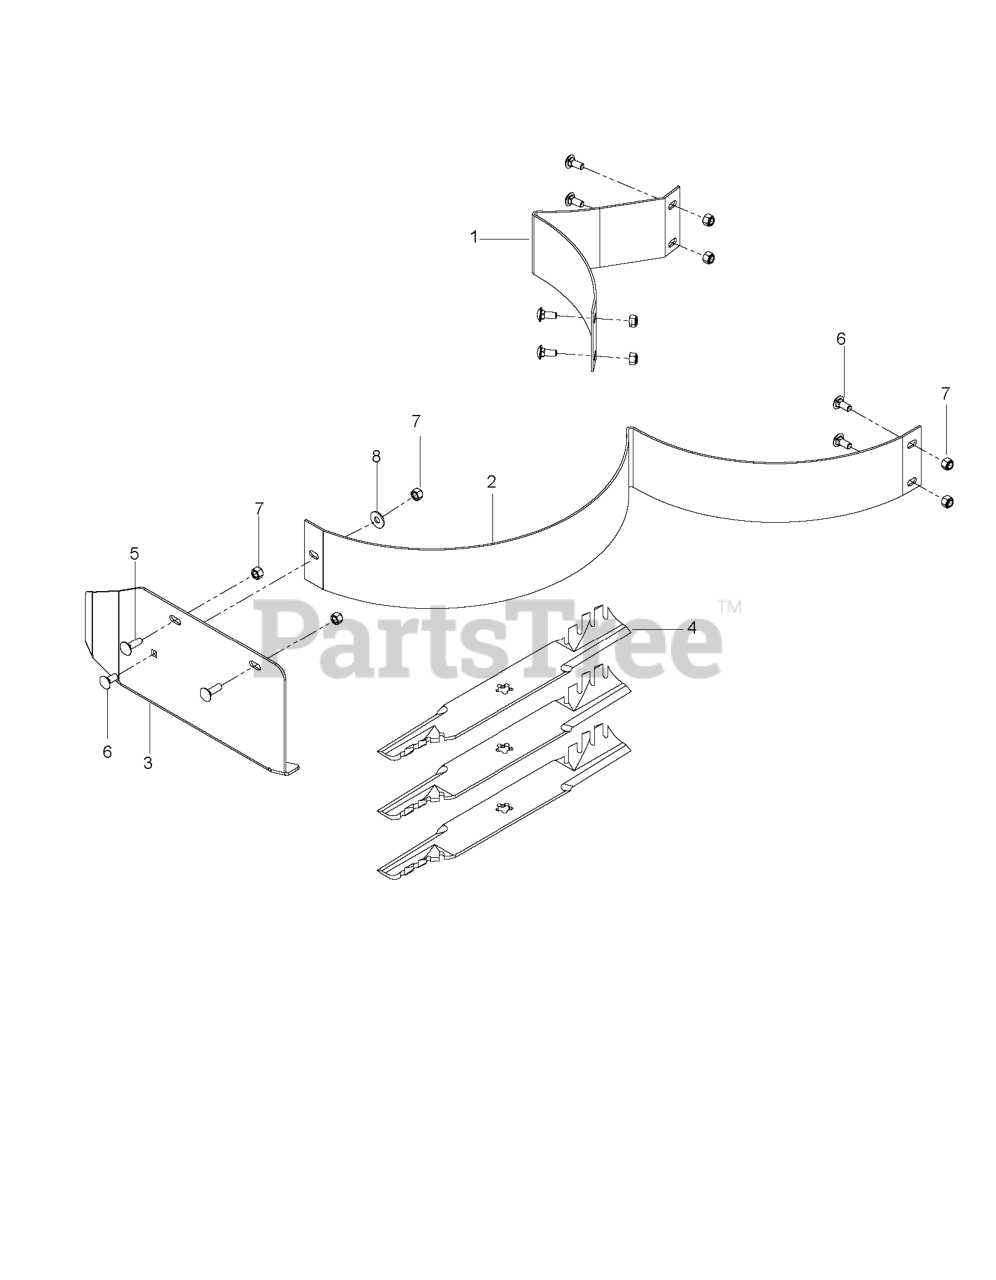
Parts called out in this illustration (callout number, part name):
1	BAFFLE, 52 MULCH LH
2	BAFFLE, 52 MULCH RH
3	52 MULCH CAP - PAINTED
4	BLADE, 17.75" GATOR
5	RHSNB 5/16C X 1
6	BOLT 5/16C X 3/4" CARRIAGE
7	NUT 5/16 NYLOC
8	WASHER 5/16 FLAT
